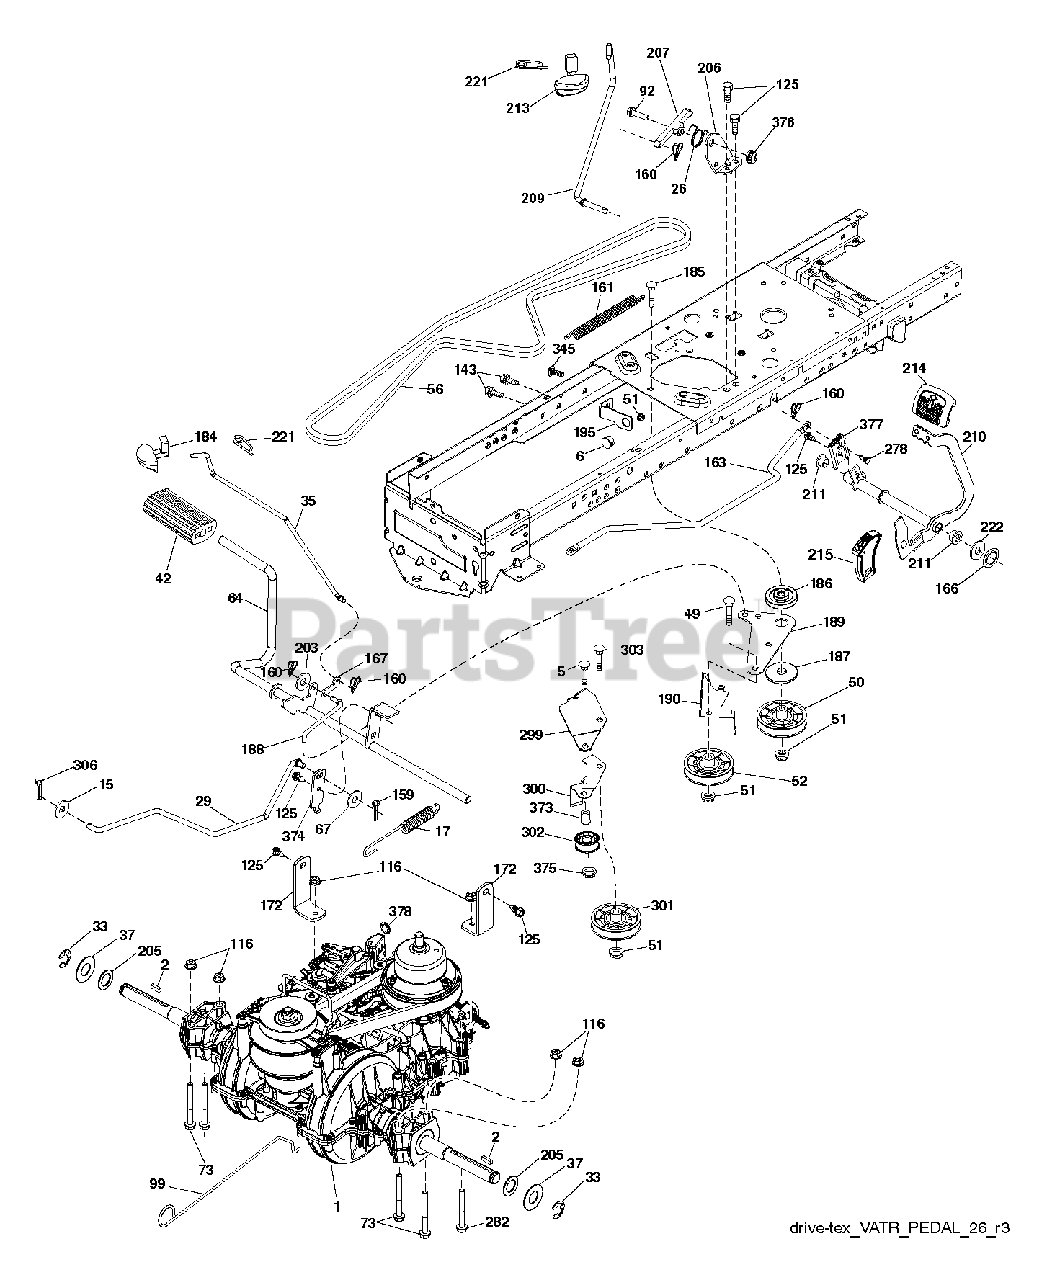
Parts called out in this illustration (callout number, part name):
2	SQUARE KEY
6	GROMMET T
17	Brake Variator Spring
26	BRKT.ANIT-ROTATION.CLUTCH
29	ROD.BRAKE.K46
33	E-RING LT
35	ROD.BRAKE.PARKING.LT.T
37	WASHER.HARDENED
49	BOLT
50	IDLER.FLAT.910.OFFSET
51	NUT LOCK FLG 3/8-16 UNC
52	IDLER.V-GROOVE.910.OFFSET
56	BELT.DRIVE.MOWER.TEX.42"
64	SUBASM.SHAFT.PEDAL.BRAKE
67	WASHER
73	BOLT HEX 5/16-18 GR 5
92	BOLT
99	ROD.BYPASS.VARIATOR.GEN2
116	NUT LOCK HEX FLANGE 5/16-18
125	SCREW
143	SCREW LT
159	COTTER PIN
160	RETAINER CLIP
161	SPRING, RETURN LT
163	ROD.CONTROL.PEDAL.VARIATOR
166	NUT.PUSH.625
167	LATCH.BRAKE.SPRING
172	STRAP.TORQUE.VARIATOR
184	HANDLE.PARKING.BRAKE.LTTEX.667
186	SPACER.RETAINER
187	WASHER 12/32X2X10GA
188	LINK.CLUTCH.GROUND.DRIVE
189	BELLCRANK.GROUND.DRIVE.TEX.
190	KEEPER.BELLCRANK.DRIVE
195	BRACKET.BRAKE.BRAKE.VAR.SD
203	WASHER
206	BRACKET.MOUNT.CRUISE.LATCH
207	LATCH.CONTROL.CRUISE.VARIATOR
210	WELDMENT.PEDAL.VARIATOR
211	BEARING.NYLON
213	HANDLE.CONTROL.CRUISE.ELTE
214	PEDAL.FORWARD.PAD.TEX
215	CAP.PEDAL.REVERSE.VARIATOR
221	RETAINER.SPRING.CLIP.H
222	WASHER 21/32 X 1-1/4 X 10 GA.
278	Cruise Variator Bolt
282	BOLT HEX FLGHD 5/16-18X3 GR. 5
299	BRACKET.MOUNT.IDLERS
300	KEEPER.IDLERS.REAR.VARIATOR
301	PULLEY.IDLER.V-GROOVE
302	PULLEY.IDLER.FLAT.2"
303	BOLT CARRIAGE
306	PIN COTTER
373	SPACER.IDLER
374	ARM.CONTROL.BRAKE
375	LOCKNUT
376	NUT.FLANGE.HEX.5/16X18.BLACK
377	GEAR.SECTOR.CONTROL.CRUISE.VAR
378	NUT.PUSH.8MM
